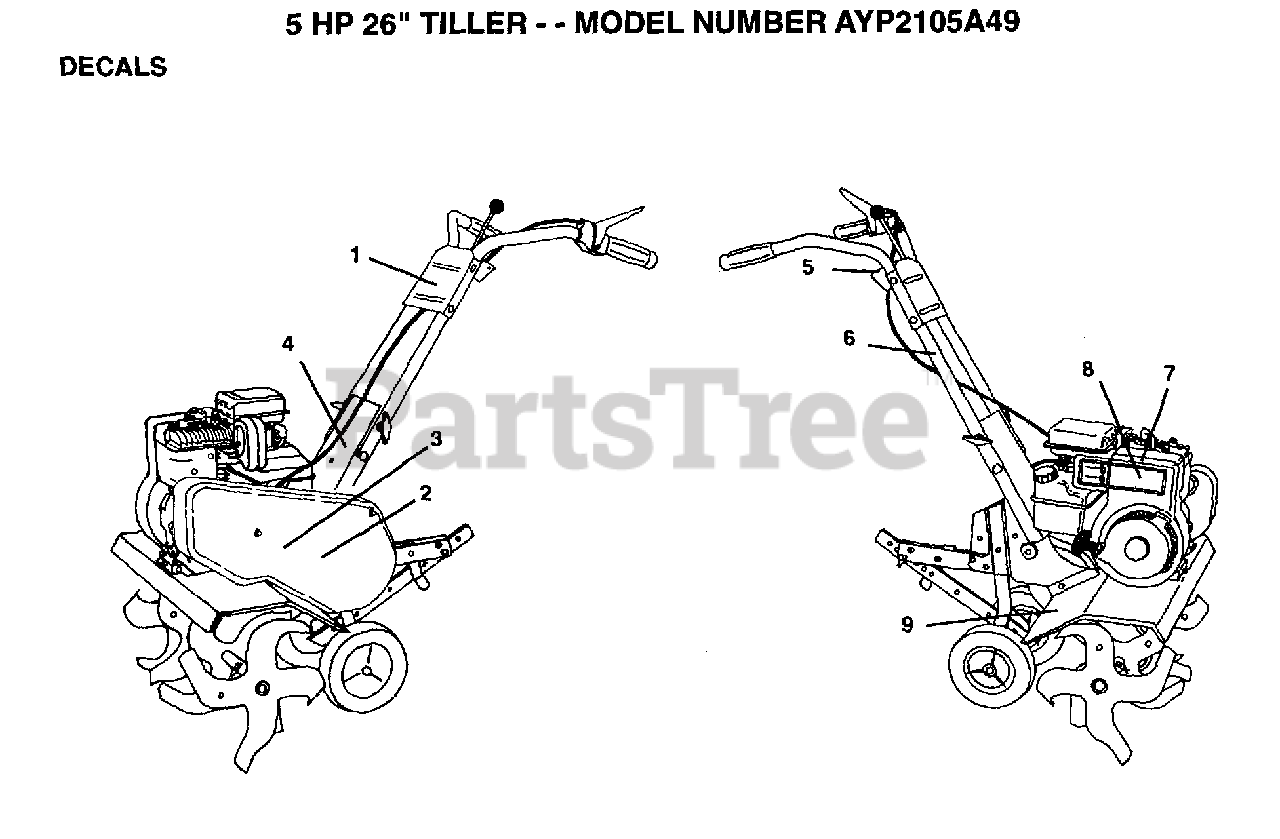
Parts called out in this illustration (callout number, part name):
1	DECAL CTRL PANEL
2	DECAL LOGO GUARD
5	DECAL REVERSE
6	DECAL TI
9	DECAL TI
